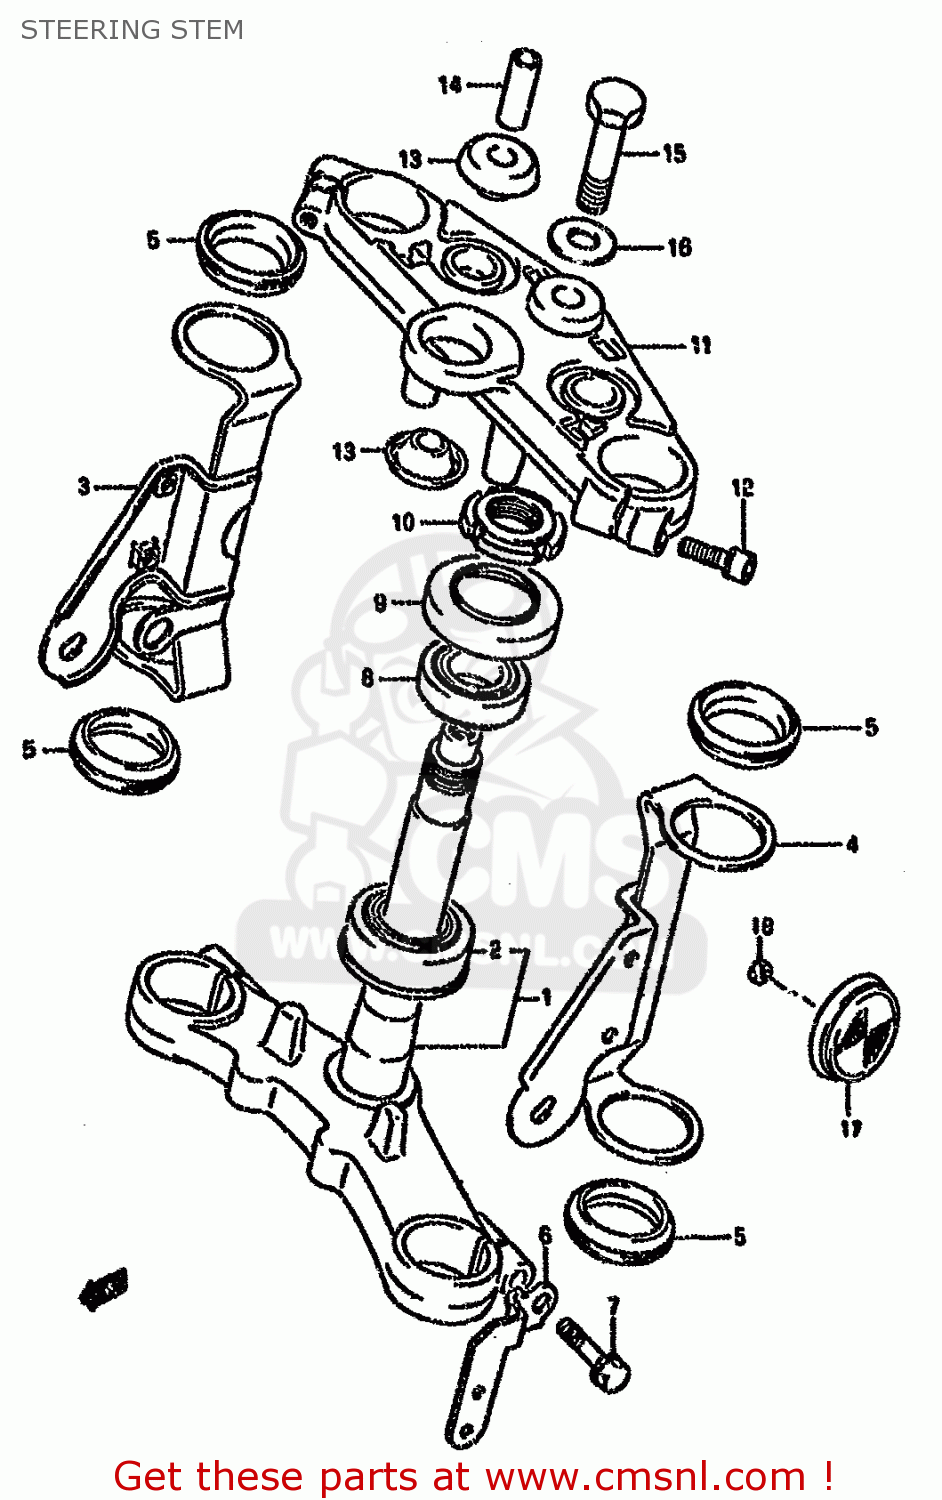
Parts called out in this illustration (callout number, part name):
1	STEM,STEERING
2	BEARING(30X55X17)
3	BRACKET,HEADLAMP,R
4	BRACKET,HEADLAMP,L
5	CUSHION,HEADLAMP BRACKET
6	BRACKET,FR SIDE RR,R
7	BOLT,STEERING STEM
8	TAPER,ROLLER BEARING
9	DUST SEAL,STEERING UPR
10	NUT,STEERING STEM(25X44X10)
11	HEAD,STEERING STEM
12	BOLT
13	CUSHION,UPR BRACKET
14	SPACER,STEERING STEM HEAD
15	BOLT
16	WASHER,STEM HEAD(10.5X30X3.2)
17	REFLECTOR,REFLEX FR
18	NUT
